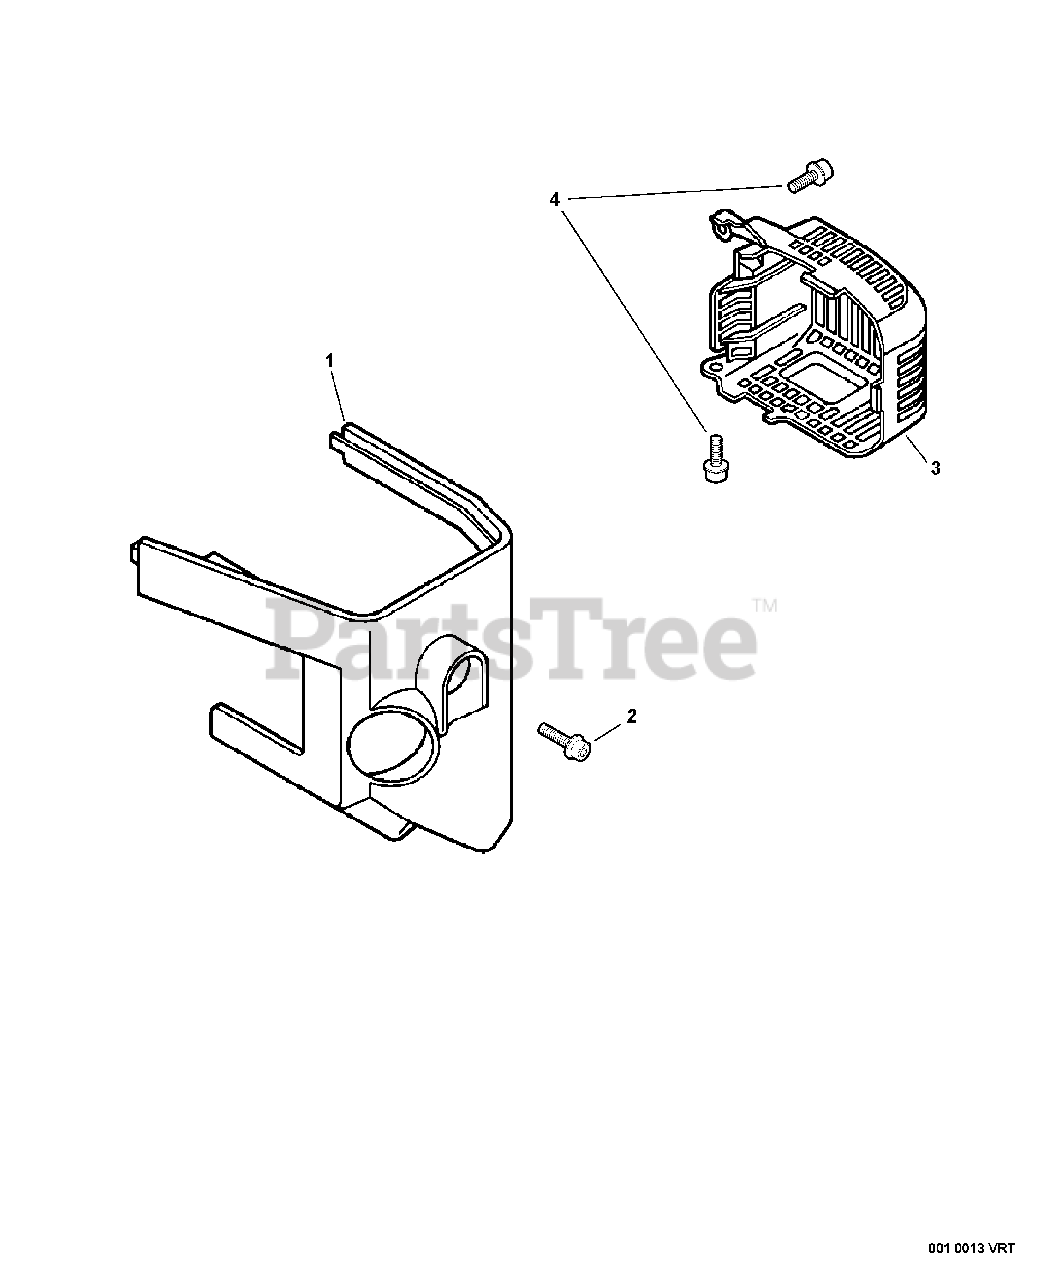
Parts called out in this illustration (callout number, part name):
1	COVER, ENGINE
2	SCREW - 5X12
3	COVER, EXHAUST
4	SCREW - 5X16
